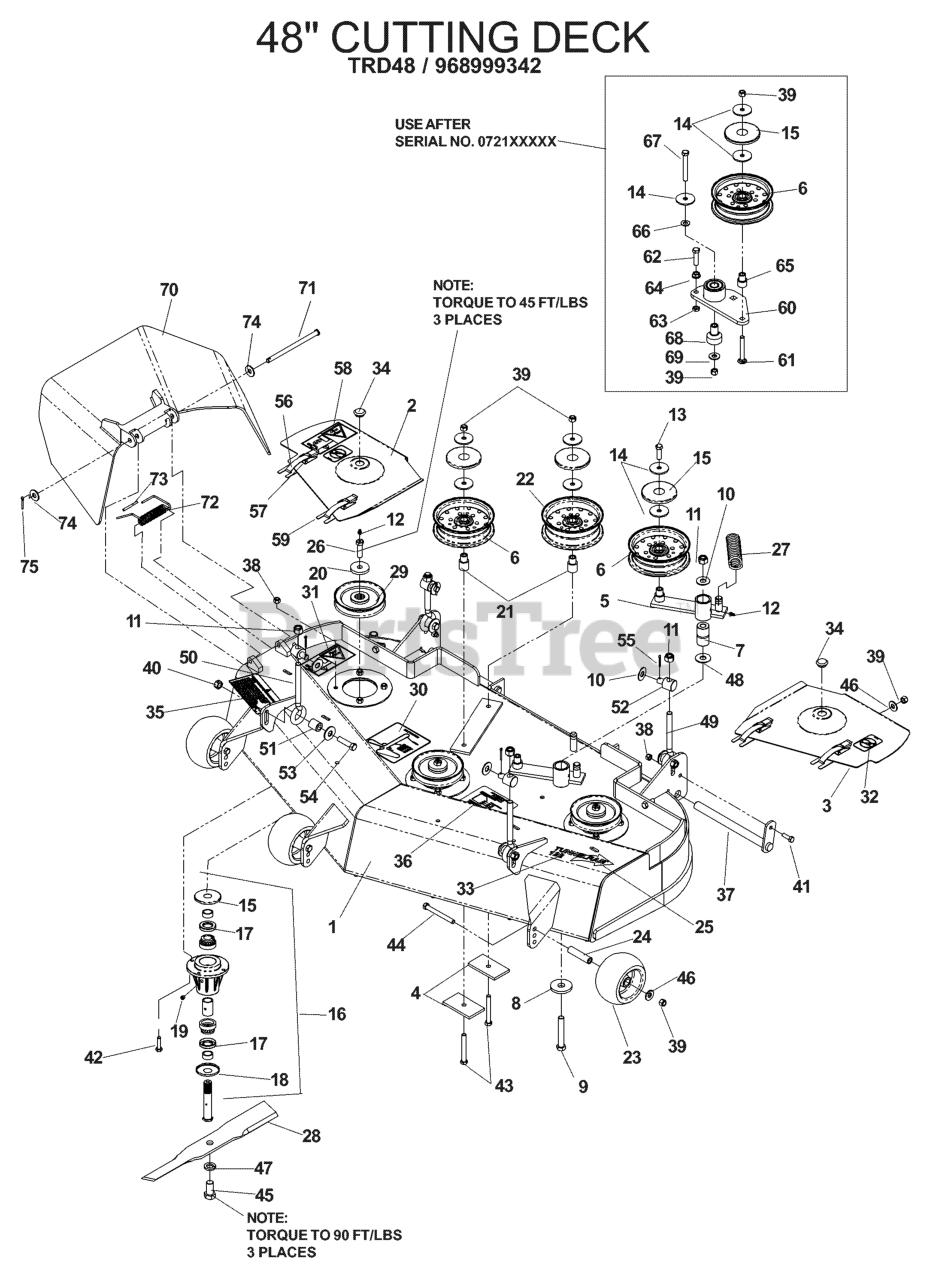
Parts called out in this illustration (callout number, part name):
1	DECK W/DECALS 48" HUS
4	SUPPORT PLATE
6	IDLER PULLEY
7	PIVOT BUSHING
8	WASHER, SUPPORT
9	HCS 1/2C X 3 1/4
10	WASHER 1/2 FLAT
11	NUT 1/2-13 HEX NYLOC ZD
12	ZERK
13	HCS 3/8C X 1 1/4 GR5
14	WASHER, 3/8 SPEC
15	TOP DUST CAP
16	HOUSING ASM, 52/61
17	SHAFT SEAL
18	BOTTOM DUST CAP
19	PLUG-VENTED
20	SPINDLE WASHER
21	IDLER BUSHING
22	IDLER PULLEY (TALL)
23	ANTI-SCALP ROLLER
25	DECAL, TUNNEL RAM 6"
26	HCS 7/16-20 GD 8 SPEC
28	BLADE, 16-1/4"
29	PULLEY 42-48
30	DECAL, BELT ROUTING
31	DECAL, EURO SEVERING
32	DECAL, NO STEP
33	DECAL, 122
34	PLUG, BUTTON HOLE
35	DECAL, DISCHARGE, MULTILINGUAL
36	DECAL, ANTI SCALP
38	NUT 5/16 NYLOC
39	NUT 3/8-16 NYLOC
40	NUT 7/16C CENTERLOCK
41	HCS 5/16C X 1
42	HCS 5/16C X 1 1/4
43	HCS 3/8C X 3
44	HCS 3/8C X 3 1/2
45	HCS 5/8F X 1 1/4
46	WASHER 3/8 FLAT
47	LOCKWASHER 5/8
48	WASHER 1/2 X 1.44 HRD ZD
50	EYEBOLT, 1/2-13 X 5.88
53	SPRING WASHER - .50
54	HCS 7/16 - 14 X 1 3/4
55	PIN COTTER 1/8 X 1 ZD
56	DRAW LATCH
57	RIVET, BLIND, 5/32 DIA
58	DECAL, EURO SEVERING
60	ARM-IDLER W/BRG
61	RHSNB 3/8-16 X 2.75
62	HCS 3/8-16 X 1-1/2
63	NUT 3/8-16 HEX JAM
64	NUT 3/8C WHIZ
65	BUSHING, IDLER
66	WASHER 3/8 SAE FLAT
67	HCS 3/8C X 3
68	PIVOT, BEARING
69	WASHER 3/8 FLAT
70	DISCHARGE CHUTE 48"
71	PIN-CLEVIS 5/16 DIA X 5.19 ZD
72	SPRING - TORSION
73	CAP-SLEEVE
74	FLAT WASHER 5/16 SAE
75	RP_COTTER PIN 1/8 X 3/4
